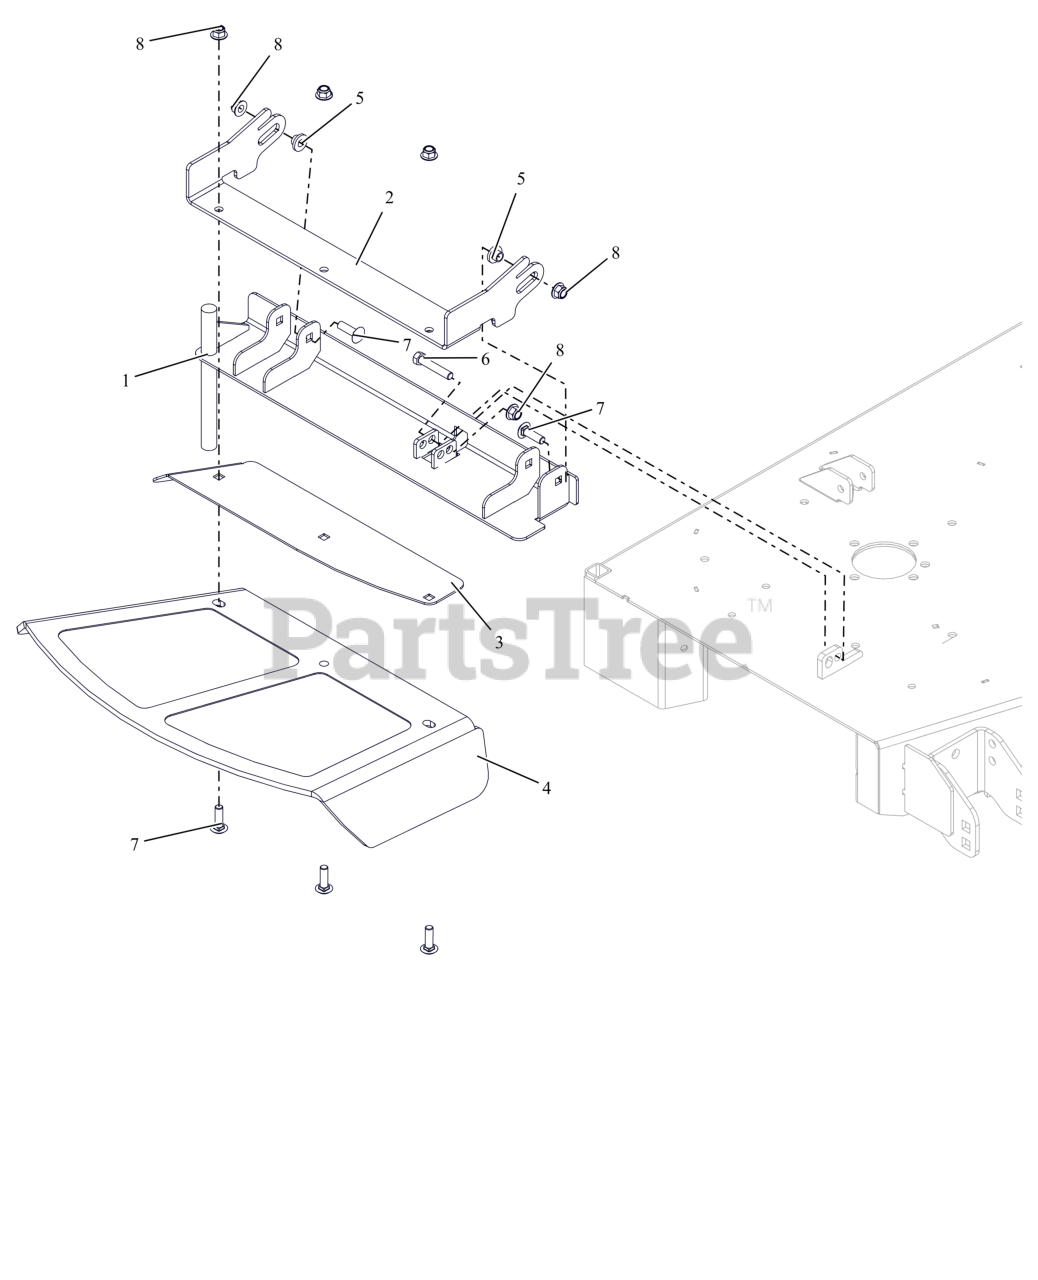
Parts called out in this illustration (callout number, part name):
1	44-60 DISCH CHT WMT ORG W/SAFE
2	48-60" CHUTE MTG BRKT -ORG
3	48-60 DISCH CHUTE CLMP PLT-ORG
4	CHUTE,48-60" FRMD RUBBER DISCH
5	BSHG-FLG .385X.500X.875X.406
6	BLT,HEX .38-16X2.00 G5 ZCC
7	BLT,RHSSN .38-16X1.25 G5 ZCC
8	NUT,NYL-FLG .38-16 GF ZCC
